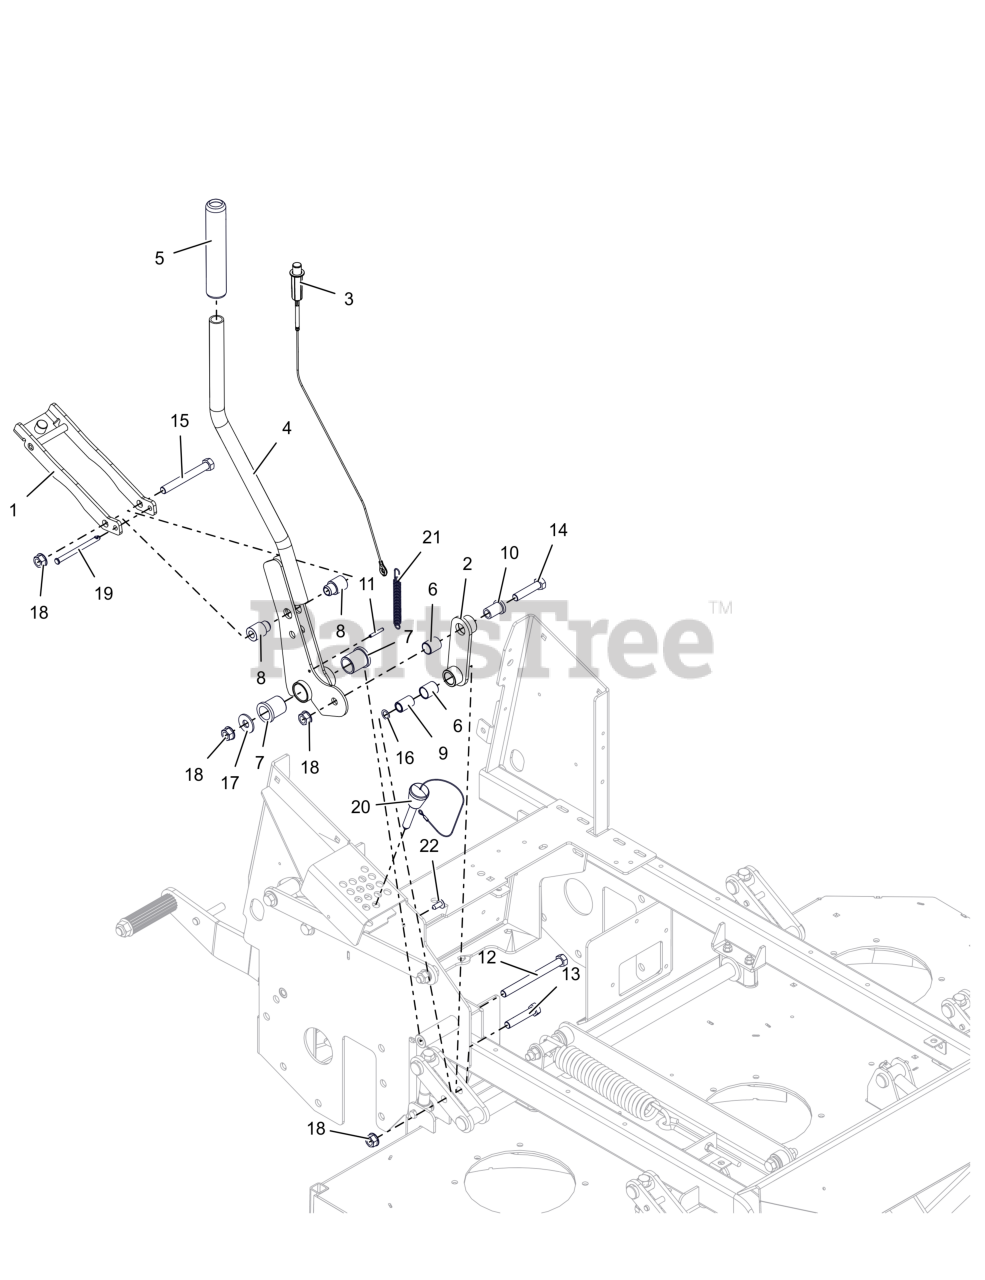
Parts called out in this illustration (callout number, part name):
1	WLDMT, HOC BRACKET
2	LINK, HOC LEVER
3	CABLE, HOC PUSH CONTROL
4	WLDMT, HOC LEVER (BLACK)
5	GRIP, DECK LIFT
6	BRG, .750 X .875 X 1.000
7	BSHG-FLG 1.00X1.25X1.50X1.50
8	BSHG,FLG
9	SPCR, SLV .532 X .750 X 1.150
10	BSHG-FLG .515X.746X1.290X1.000
11	PIN-ROLL .188X1.25
12	BLT,HEX .50-13X5.50 G5 ZCC
13	BLT, HEX .50-13X2.50 G5 ZCC
14	BLT, HEX .50-13X2.25 G5 ZCC
15	BLT, HEX 0.5-13X4.25 GR5 ZCC
16	WASHER, .500X.750X.020 THRUST
17	WSHR,FLT .563X1.375X.109 ZCC
18	NUT-LK-CTR-FLG .500-13 GG ZCC
19	PIN, SLIC-.3125X4.015X3.625 -ZCC
20	PIN- MAGNETIC .50X2.70
21	SPRING,EXT,.061X.50X3.0
22	XMAS TREE FASTNER-BLACK
